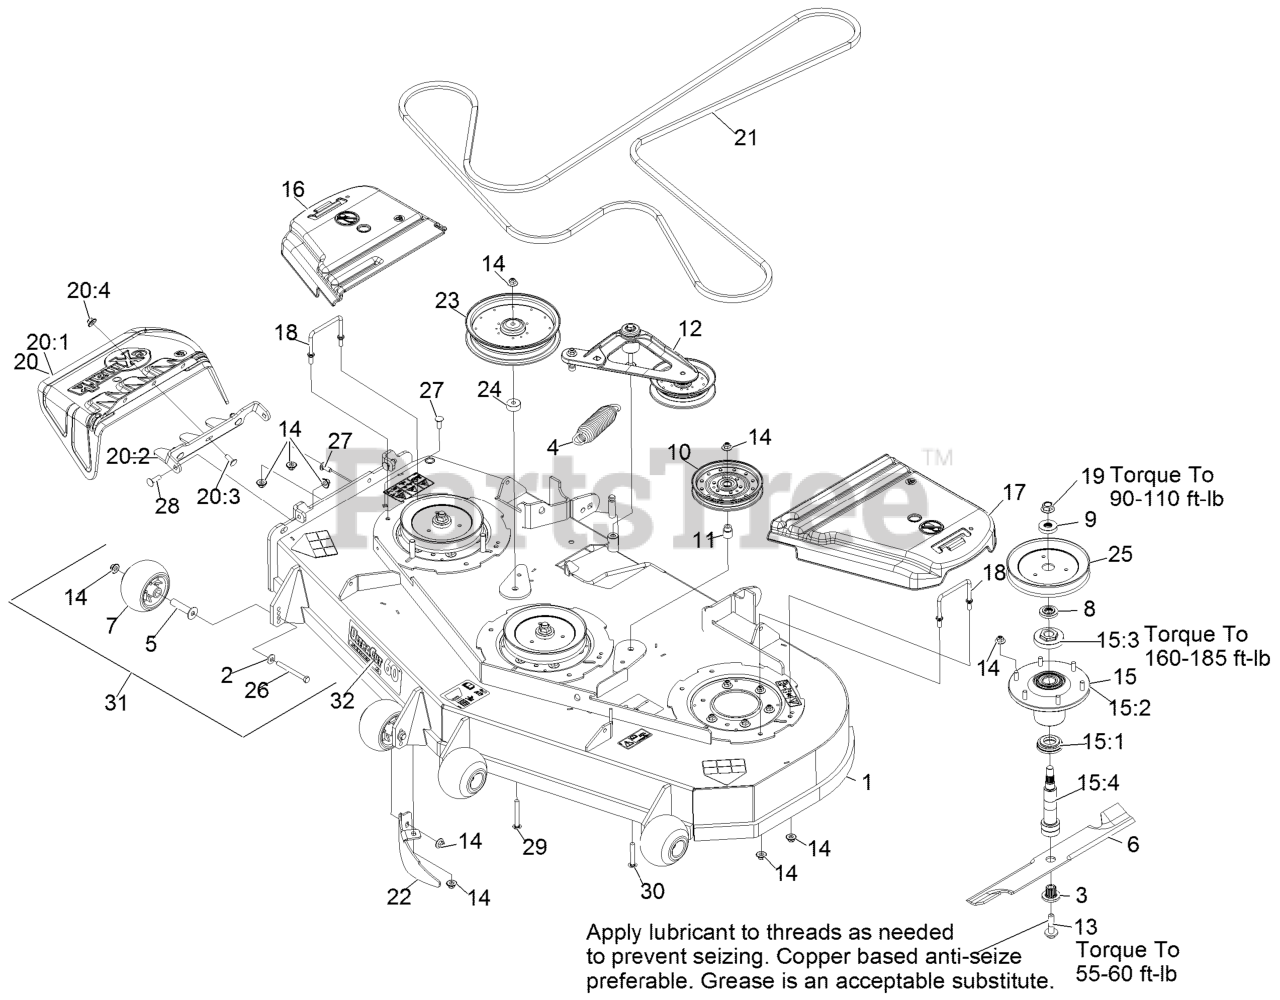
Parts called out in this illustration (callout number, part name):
1	DECK ASM,W/DECALS 60
2	WASHER-BELLEVILLE
3	BUSHING,SPLINED
4	SPRING-EXTENSION
5	AXLE, ROLLER
6	Blade-Extreme 2, 20.50"
7	ROLLER-SCALP, ANTI
8	SPACER,SPLINED STEPPED
9	SPACER,SPLINED
11	BUSHING-IDLER
12	DECK IDLER ASM
13	SCREW,SEMS 1/2-20 X 2.19
14	Nut-Nyloc 3/8-16 Flg
15	ASM,SPINDLE HOUSING
15:1	GUARD,BOTTOM
15:2	ASM,CUTTER HOUSING
15:3	NUT, SPINDLE 7/8-14
15:4	SPINDLE,DOUBLE SPLINE
16	COVER-BELT, RH
17	COVER-BELT, LH
18	WIREFORM-COVER
19	NUT-FLANGE, CENTERLOCK
20	ASM,DISCHARGE CHUTE
20:1	CHUTE,DISCHARGE
20:2	BRACKET,DISCHARGE CHUTE
20:3	SCREW-CARR
20:4	Nut-Nyloc 3/8-16 Flg
21	BELT,V-5V-198.75
22	DOGLEG - LZ60
23	PULLEY-IDLER
24	SPACER-IDLER
25	SHEAVE,BLADE DRIVE 7.25
26	SCREW-HH 3/8-16 X 3 3/4 GR 8
27	SCREW-CARR
28	Bolt-Carriage 3/8-16 X 1 1/4
29	SCREW-CARR
30	SCREW-CARR
31	KIT, ANTI-SCALP ROLLER
32	DECAL,ULTRACUT 60 SERIES
